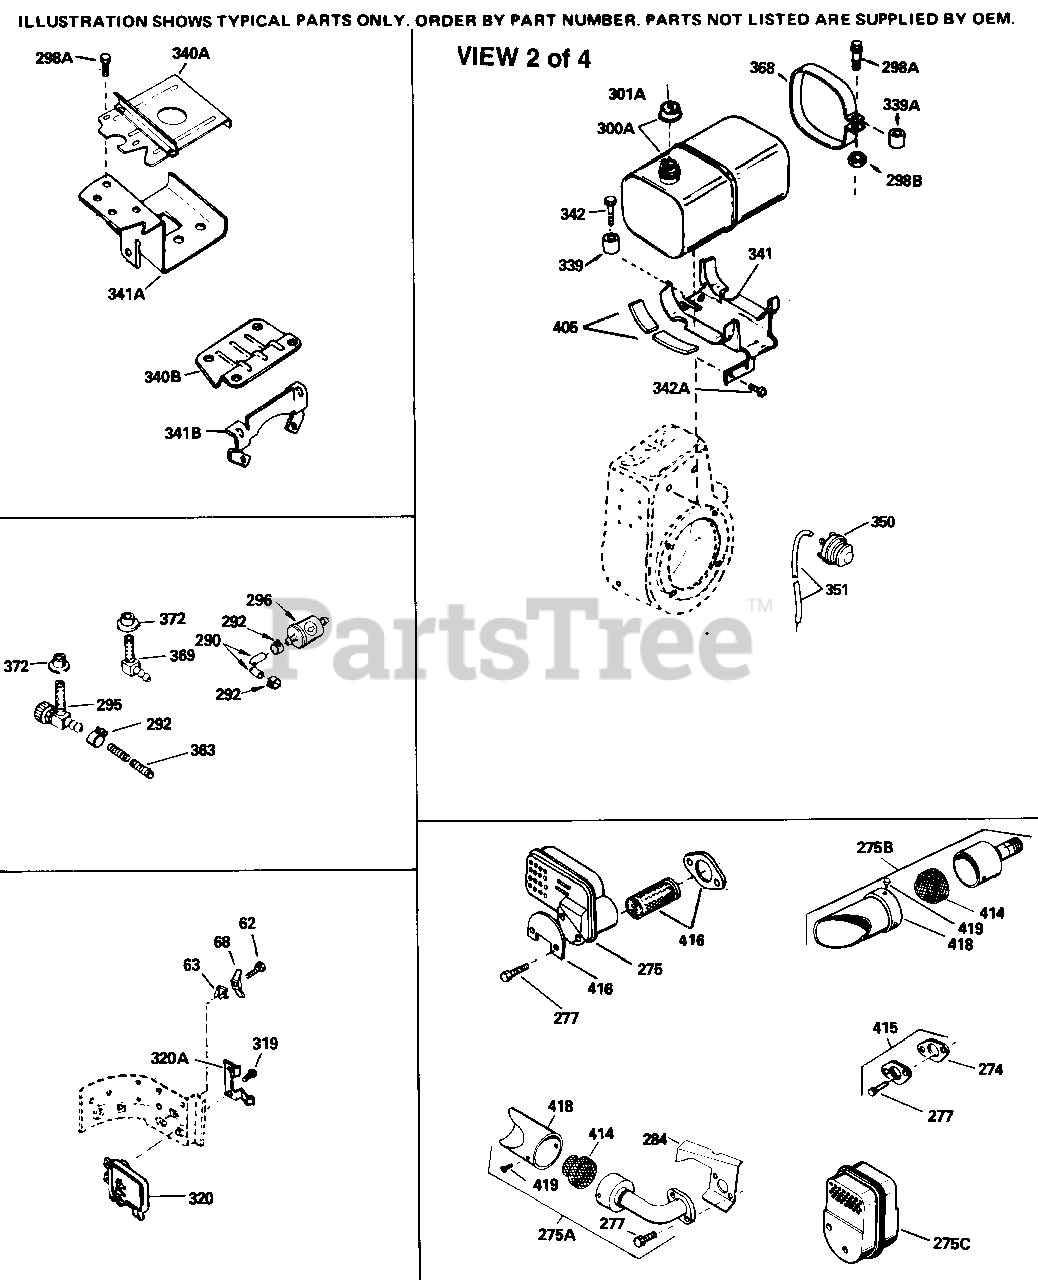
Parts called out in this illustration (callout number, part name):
37A	Lock Nut, 8-32
62	Screw, 8-32 x 3/8"
63	Breather Tube Grommet
68	Tab, Ground terminal
222A	Pop Rivet (Can be purchased locally)
241	Bracket, Air cleaner
274	Gasket, Exhaust
275B	Muffler (Incl. 284, 284A & 416) (This spark arrester mufflercan be used on any model.)
277	Screw, 5/16-18 x 3-3/16" Use as requi red
277	Screw, 5/16-18 x 4-1/4" Use as requir ed
290	Fuel Line (8.62") equired)
290	Fuel Line (Braided 32")(80cm) As requ ired
292	Fuel Line Clamp
301A	Fuel Cap (Red 1-1/2" ID) (also availa ble in Packaged Part #740005B) (Red Plastic) (Spurt Resistant, Low Profil e) (Use as required) (1.5" I.D.)
301A	Fuel Cap (Red Plastic) (Spurt Resista nt, High Profile) (Use as required) ( 1.5" I.D.)
301A	Fuel Cap (Red)
301A	Fuel Cap (White Plastic)(Standard) (U se as required) (1.5" I.D.)
338A	Plug, Cover
341	Bracket, Lower fuel tank mtg.
342	Screw, 1/4-20 x 5/8"
414	Opt.Muffler Screen Mini-Bike applica tion
415	Kit, Exhaust adapter Incl. 274 & 277
418	Cover & Tube, Muffler use as require d
419	Screw, 8-18 x 3/8" (use as required)
421	SAE 5W30 4-Cycle Engine Oil - Quart - Winter
422	Muffler Optional
